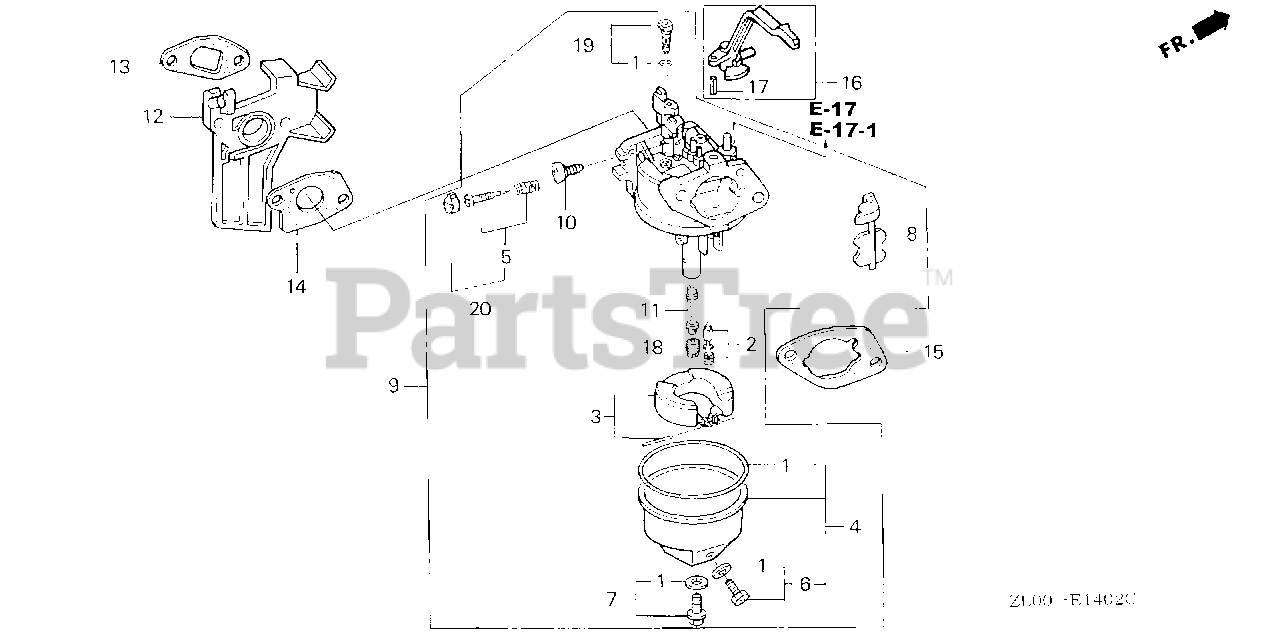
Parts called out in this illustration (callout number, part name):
1	GASKET SET
2	VALVE SET, FLOAT (SEAT NOT INCLUDED)
4	CHAMBER SET, FLOAT
6	SCREW SET, DRAIN
7	SCREW SET
9	CARBURETOR ASSY. (BE74A C)
10	SCREW, THROTTLE STOP
11	NOZZLE, MAIN
12	INSULATOR, CARBURETOR
13	GASKET, INSULATOR
14	GASKET, CARBURETOR
15	GASKET, AIR CLEANER
16	LEVER, CHOKE
17	PIN, SPRING (2X12)
18	JET, MAIN (#72)
18	JET, MAIN (#75)
18	JET, MAIN (#78)
19	JET SET, PILOT (#40)
20	SCREW SET, PILOT
